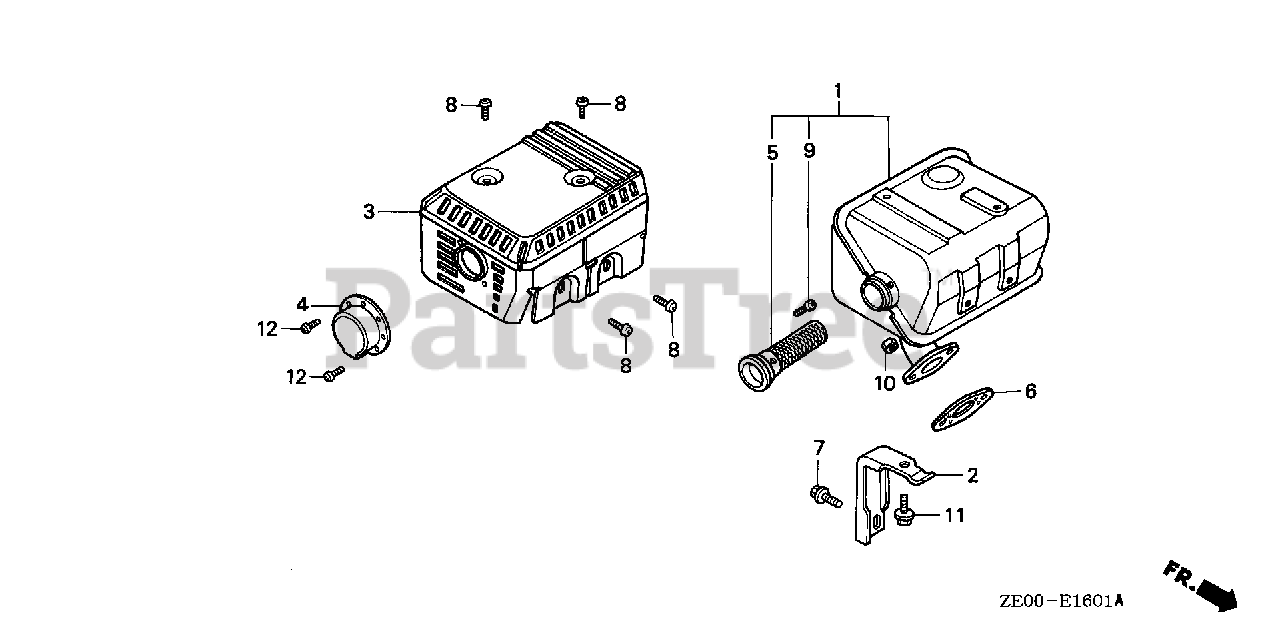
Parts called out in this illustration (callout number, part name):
1	MUFFLER (SILENT)
2	STAY, MUFFLER
3	PROTECTOR, MUFFLER (SILENT)
4	CAP, MUFFLER
5	ARRESTER, SPARK (SILENT)
6	GASKET, MUFFLER
7	BOLT, FLANGE (6X13) (CT200)
8	SCREW, TAPPING (5X8)
9	SCREW, TAPPING (4X6)
10	NUT, HEX. (8MM)
11	BOLT, FLANGE (6X12)
12	SCREW, TAPPING (4X6)
